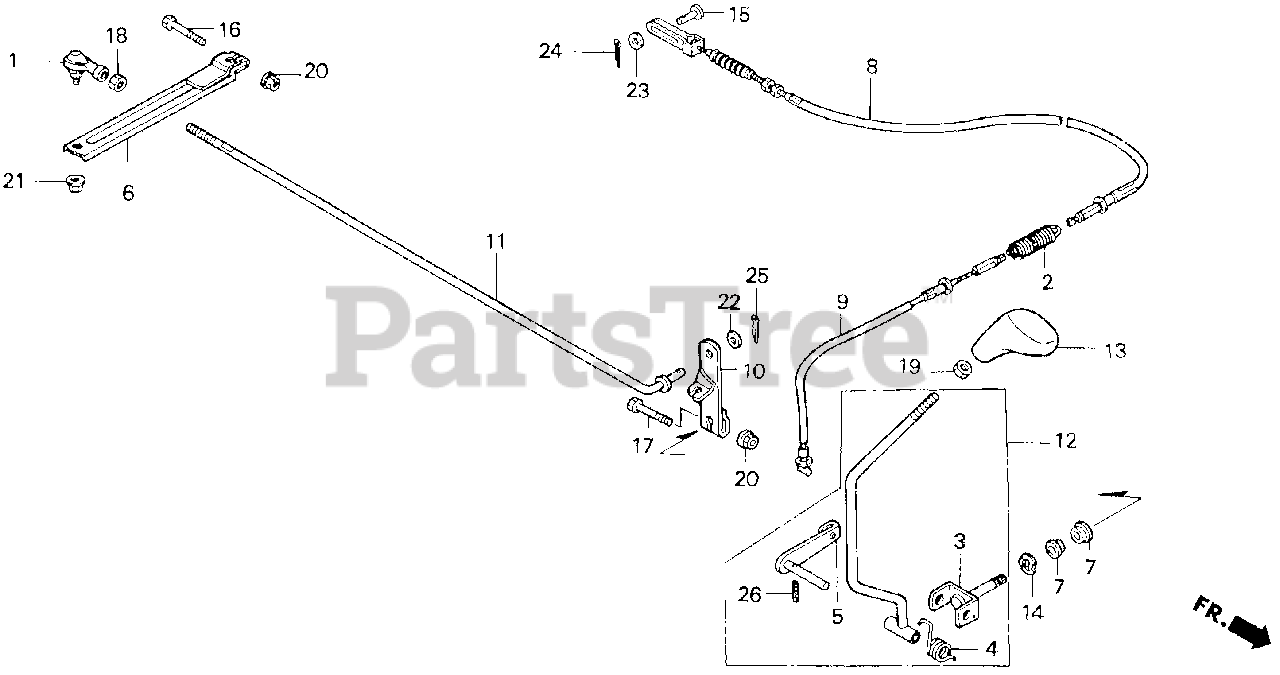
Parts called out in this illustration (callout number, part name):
1	JOINT, R. BALL
2	SPRING, CLUTCH DAMPER
3	SHAFT, CHANGE LEVER
4	SPRING, CHANGE LEVER
5	LINK, CLUTCH
6	ARM, TRANSMISSION CHANGE
7	BUSH (15X19X18)
8	CABLE C, CLUTCH (CHANGE)
9	CABLE D, CLUTCH (CHANGE)
10	ARM, CHANGE
11	ROD, CHANGE (C)
12	LEVER ASSY., CHANGE
13	KNOB, SHIFT LEVER
14	WASHER, WAVE (15MM)
15	PIN, CLUTCH JOINT
16	BOLT, HEX. (6X32)
17	BOLT, HEX. (6X38)
18	NUT, HEX. (8MM)
19	NUT, HEX. (12MM)
20	NUT, FLANGE (6MM)
21	NUT, FLANGE (8MM)
22	WASHER, PLAIN (8MM)
23	WASHER, PLAIN (6MM)
24	PIN, SPLIT (1.6X12)
25	PIN, SPLIT (2.0X15)
26	PIN, SPRING (5X25)
